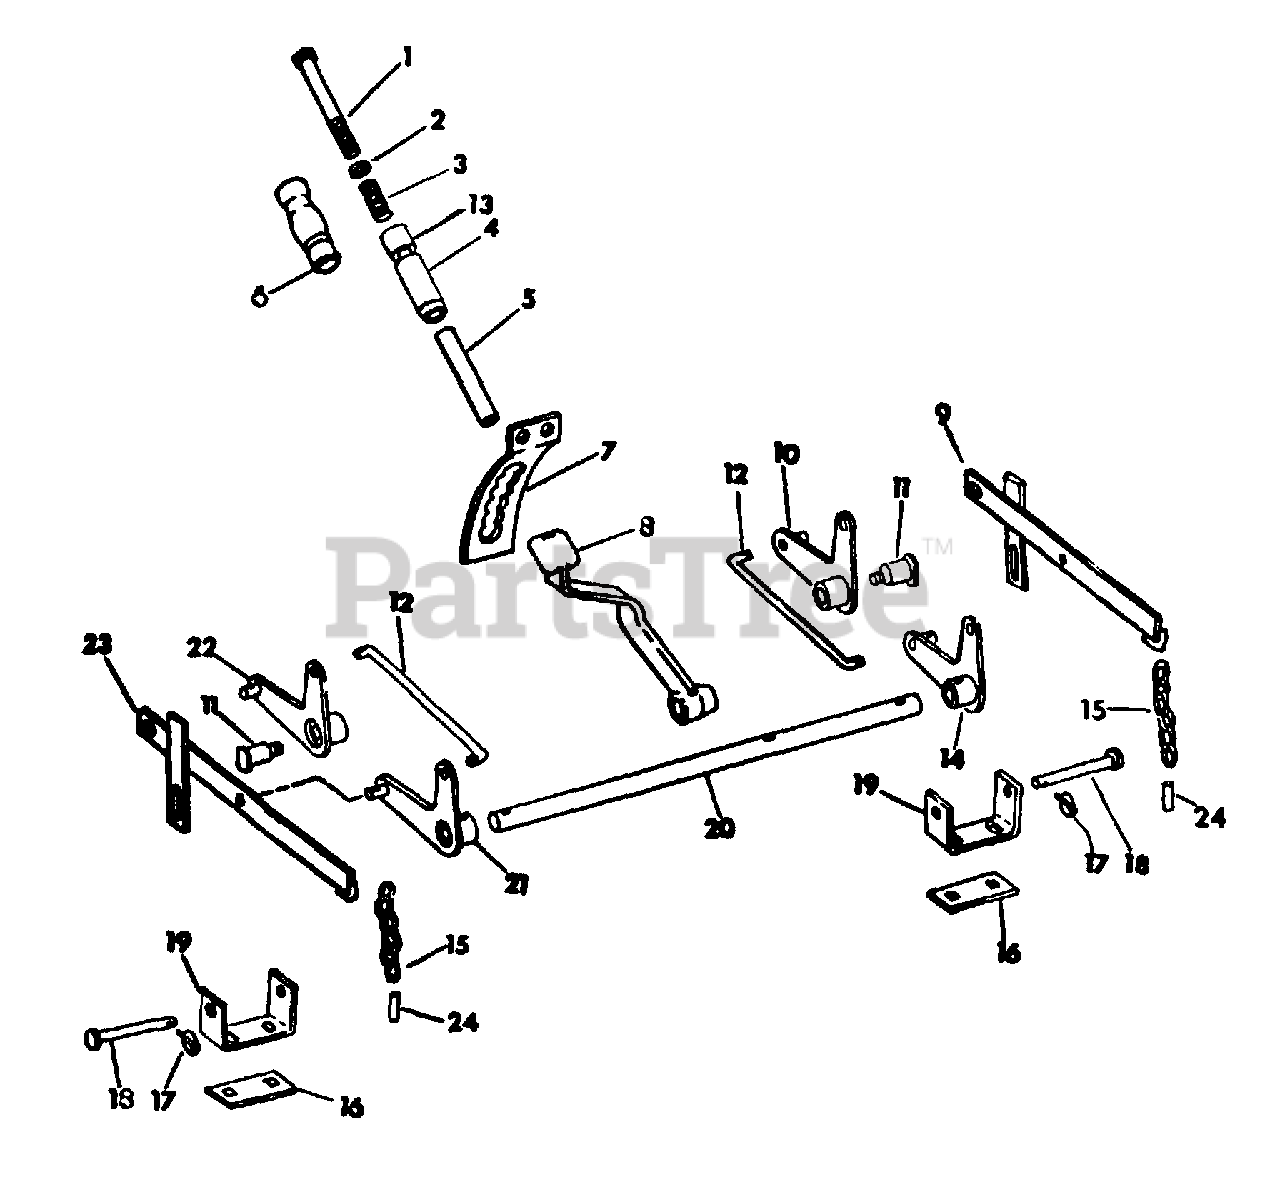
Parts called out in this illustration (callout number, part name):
1	SCREW, 3/8-16 X 6-1/4 ZND HEX-HD CAP
2	WASHER, SPRING RETAINING
3	SPRING, COMPRESSION
4	BUSHING. LIFT
5	BUSHING, LIFT HANDLE
6	GRIP, HANDLE
7	SECTOR, LIFT HANDLE
9	SUPPORT ASSY, RH LIFT BAR
10	ARM ASSY, RH FRONT LIFT
12	ROD, CONNECTING LINK
13	BUSHING, LIFT HANDLE
14	ARM ASSY, RH REAR LIFT
15	CHAIN, REAR MOWER
16	PLATE, STIFFENER
17	PIN, KLIK
19	CLEVIS, LOCK PIN FRONT BRACKET
21	ARM ASSY, LH REAR LIFT
22	ARM ASSY, LH FRONT LIFT
23	SUPPORT ASSY, LH LIFT BAR
24	SPACER, 1/4 X 3/8 STD PIPE
